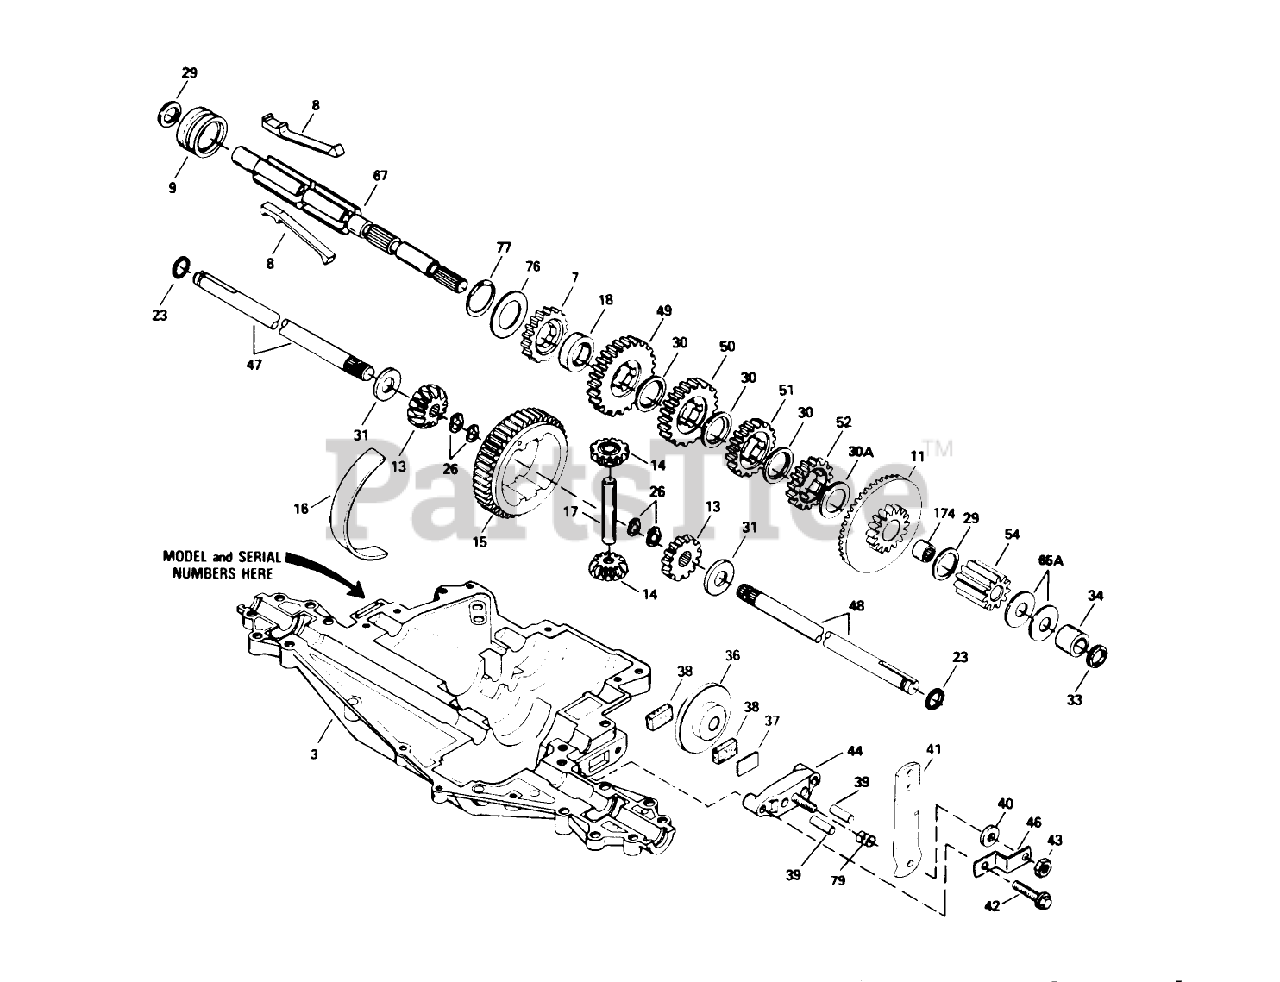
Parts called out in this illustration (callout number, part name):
3	Transaxle Case
7	Gear-Spur (22 teeth)
8	Shift Key
9	Shift Collar
11	Bevel Gear Bearing (44/16 Teeth) (Incl. Ref. #174)
13	Gear Bevel
14	Gear Pinion
15	Gear-Ring
16	Bearing Strip
17	Drive Pin
18	Neutral Spacer
23	Ring-Seal
26	Retaining Ring (pkg of 2)
29	Washer
30	Washer
30A	Washer
31	Washer
33	O-Ring
34	Bushing
36	Brake Disk
37	Brake Pad Plate
38	Brake Pad
39	Dowel Pin
40	Washer
41	Brake Lever
42	Ring Set (.020 O S)
43	Locknut
44	Nozzle-Carburetor
46	Bracket
47	Axle (16-13/16" Ig.)
48	Axle (11-5/8" long)
49	Gear-Spur, 35 Teeth
50	Gear-Spur 27 Teeth
51	Spur Gear (19 Teeth)
52	Gear-Spur 20 teeth
54	Spur Gear (11 Teeth)
65A	Washer
67	Shifter Brake Shaft
76	Washer
77	Inverted Retaining Ring
79	Piston ASM (.020 O S)
174	Needle Bearing
